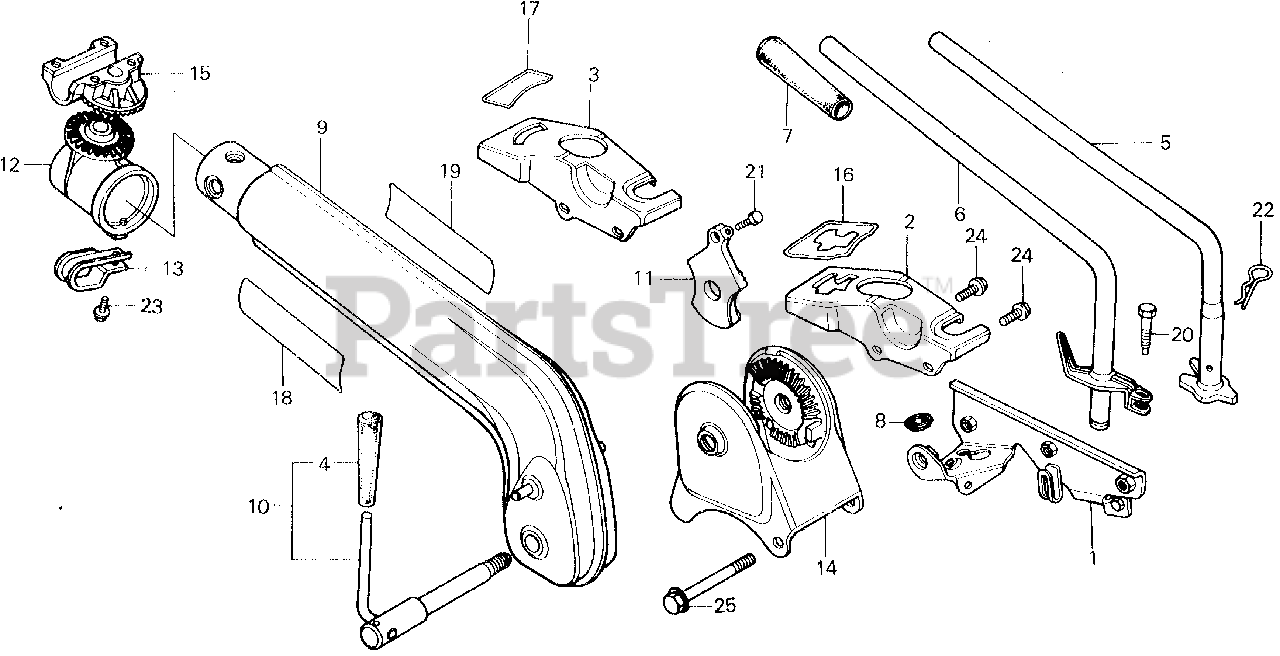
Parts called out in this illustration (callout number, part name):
1	STAY, ENGINE
3	COVER, CHANGE
4	GRIP, LEVER
6	LEVER, CHANGE (NOT AVAILABLE)
7	GRIP, CHANGE LEVER
8	GROMMET, THROTTLE CABLE
9	COLUMN, HANDLE *R8* (BRIGHT RED) (NOT AVAILABLE)
10	HANDLE, ADJUSTING
12	BASE, SWING (NOT AVAILABLE)
13	CLIP, CABLE
14	HOLDER, COLUMN
15	FRAME, SWING HANDLE
17	MARK, CHANGE
18	CAUTION, OPERATOR
19	PLATE, EX. GAS CAUTION
20	BOLT, HEX. (6X25)
21	BOLT, HEX. (6X10)
23	BOLT, FLANGE (6X10)
24	BOLT, FLANGE (6X12)
25	BOLT, FLANGE (10X95)
